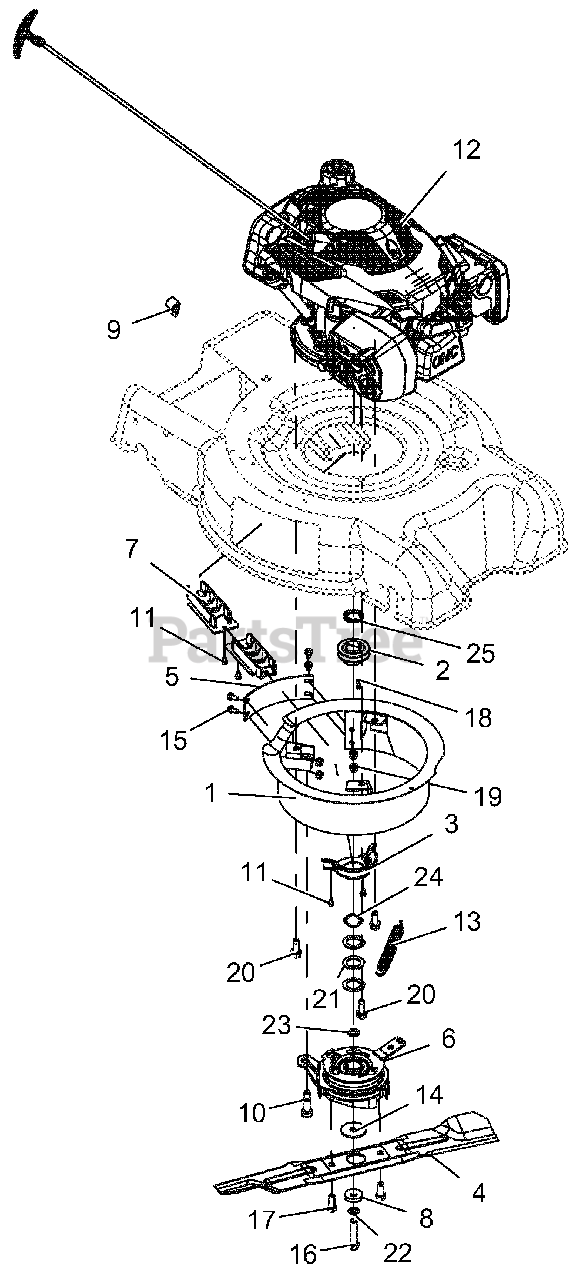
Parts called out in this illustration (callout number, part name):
1	WLDMT, ENCLOSURE - BBC
2	PULLEY, GROUND DRIVE, LM
3	GUIDE, BELT CRANKSHAFT
4	BLADE, MOWER 21" HIGH LIFT-BBC
5	BAFFLE, BBC
6	CLUTCH, RAZOR BBC
7	GUIDE, BELT INNER
8	WASHER-FLAT-STL, .44 X 1.25 X .25 YWZC
9	CLAMP, LM CABLE
10	BLT, SHLDR 12MM X 25 W/M10 THD
11	SCR, TAP 10-24X.375 PRE-COAT 80
12	ENGINE, SUBARU 175CC VERT BBC
13	SPRG, EXTENSION BBC
14	WSHR-FL-STL .469X1.75X.10 YWZC
15	BLT-HEX .25-20X.50 GR5 YWZC
16	BLT-HEX .44-20X2.00 GR5 YWZC
17	BLT-HEX M10 X 1.5X20 GR5 YWZC
18	KEY-SQ .188X.188X.625
19	NUT, LK-TOP-FLG .25-20 YWZC
20	SCR-TAP .38-16X1.00 HWH TR YZ
21	WSHR-FL-STL 1.010X1.505X.062 YWZC
22	WSHR-FL-STL .450X.750X.033 YWZC
23	WSHR-FL-STL .459X.750X.105 YWZC
24	WASHER, WAVE
25	SPCR, 1.00 X 1.375 X .179
